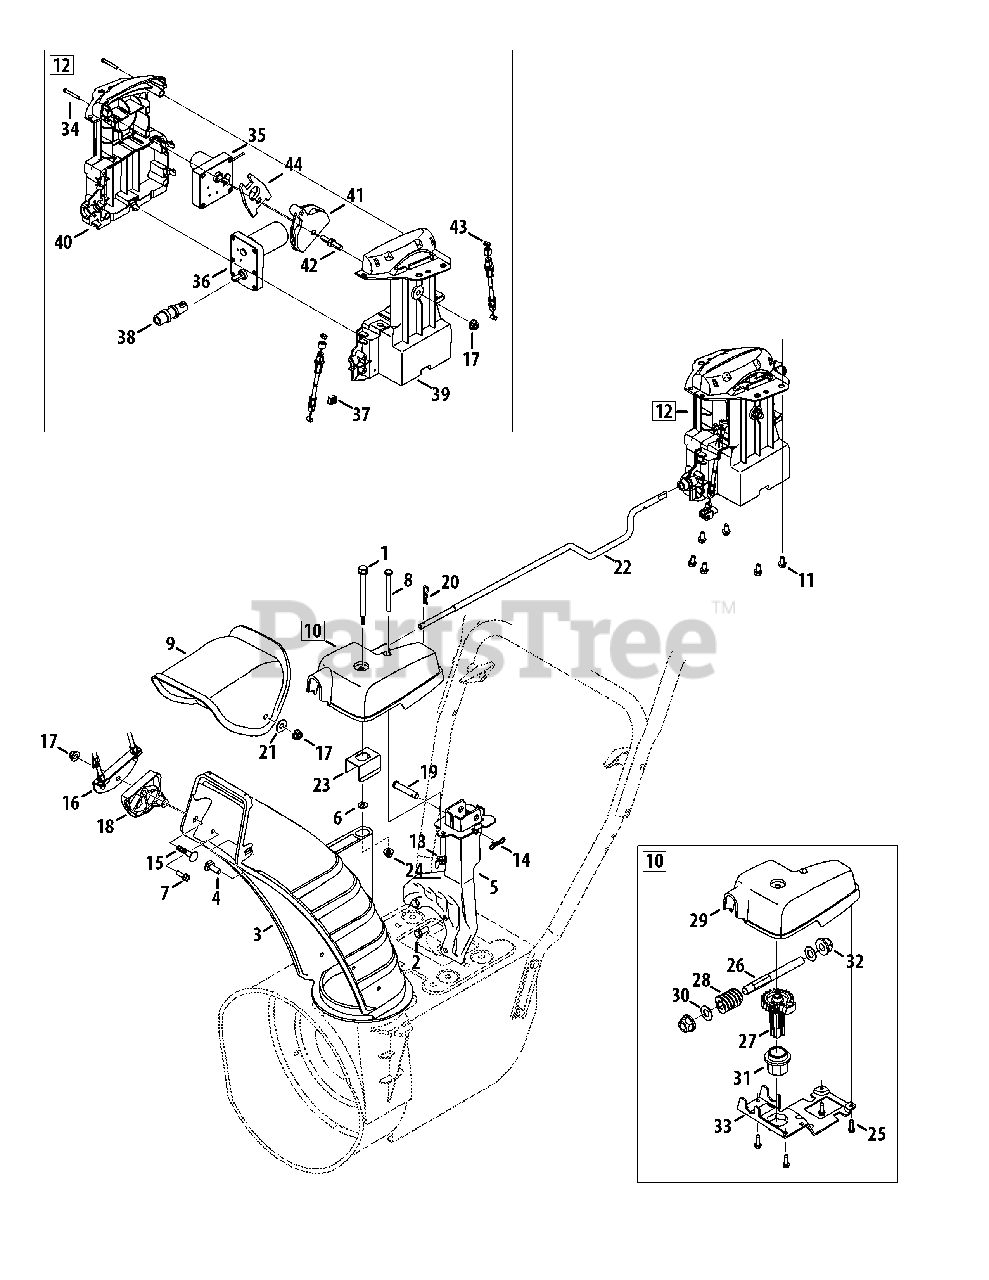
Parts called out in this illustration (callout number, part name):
1	Flange Shoulder Screw
2	Hex Screw, 5/16-24 x .750
3	Lower Chute
4	Carriage Bolt, 5/16-18 x 1.0
5	Chute Support Bracket
6	Flat Washer, .25 x .630 x .0515
7	Hi-Lo Screw, 1/4-15 x .75
8	Hex Screw, 1/4-20 x 3.00
9	Upper Chute
10	Electric Chute Gearbox Assembly
11	Hi-Lo Screw, 1/4-15 x 0.5
12	Electric Chute Control Assembly
13	Wing Nut, 1/4-20
14	Bow Tie Cotter Pin
15	Carriage Bolt, 5/16-18 x 1.50
16	Cable Bracket
17	Flange Lock Nut, 5/16-18
18	Chute Tilt Cable Guide
19	Clevis Pin
20	Cotter Pin
21	Flat Washer, .349 x .879 x .063
22	Chute Rod
23	Chute Bracket
24	Flange Lock Nut, 1/4-20
25	Screw, #12-16 x .75
26	Shaft, Worm Drive
27	Gear, Helical
28	Worm, 2-Start Nylon
29	Cover, Gear, Chute Control
30	Wash., Flat, .510 x 1.00 x .060
31	Bearing, Flange, 1.00 ID
32	Bearing, Flange, .50 ID
33	Brkt., Gear, Chute Rotation
34	Scr., AB, #10-16 x 1.25
35	Motor, Pitch, Chute
36	Motor, Rotate, Chute
37	Clip, Cable
38	Coupler, Electric Chute
39	Hsg., LH, 4-Way, Chute Control
40	Hsg., RH, 4-Way, Chute Control
41	Gde., Cbl., Chute Tilt
42	Scr., Hex, 5/16-18 x .75
43	Cbl., Snow, 4-Way, Tall Chute
44	Adpt., Pitch, Chute
